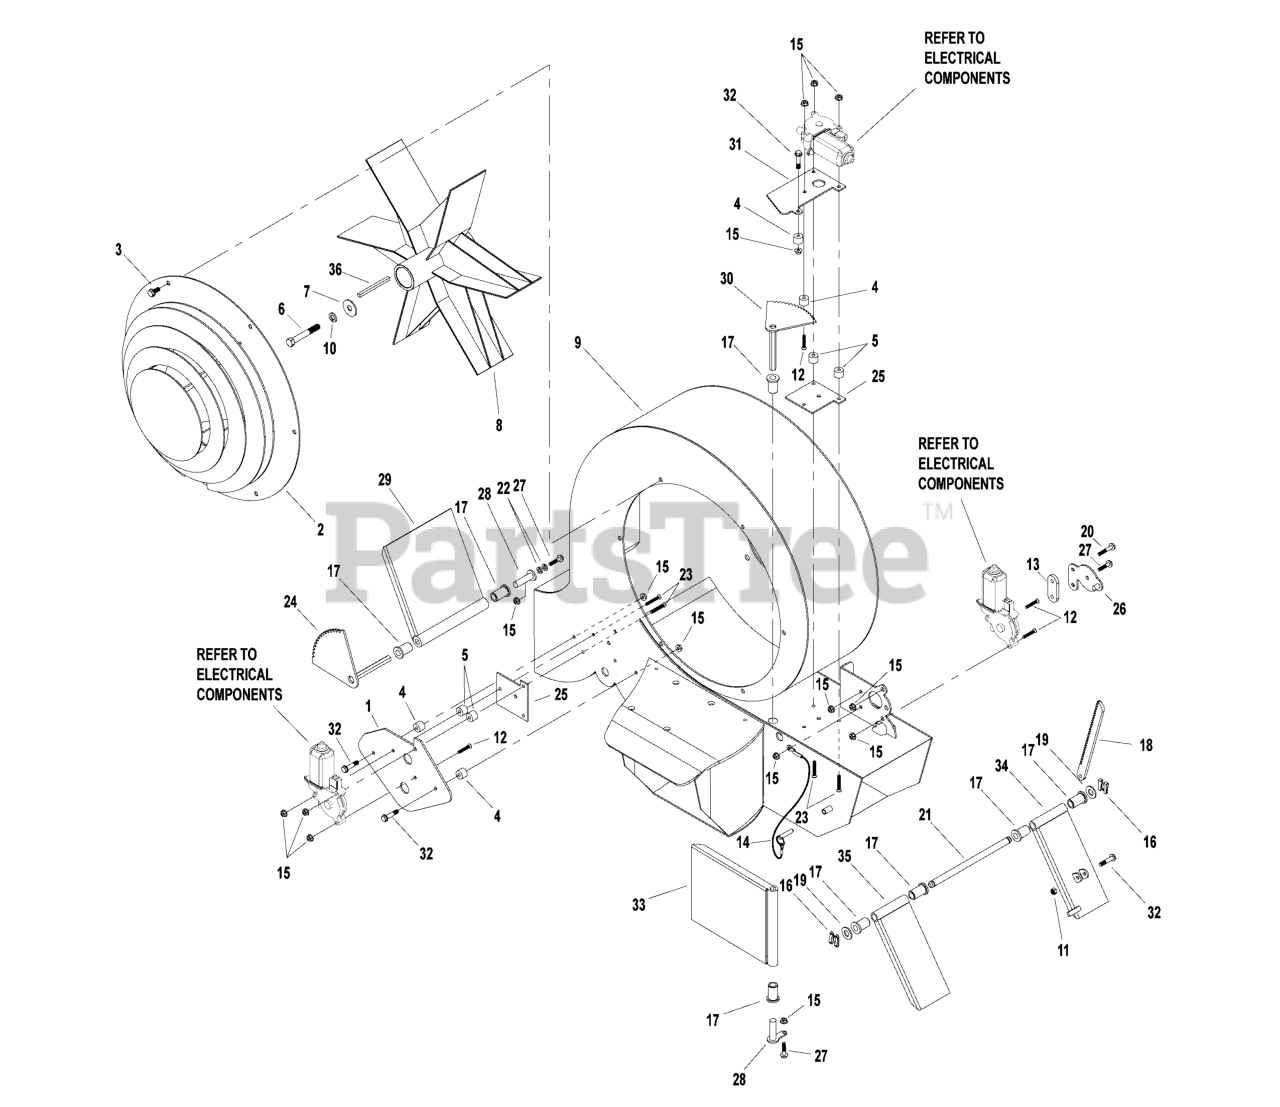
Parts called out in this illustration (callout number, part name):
1	PLATE, RIGHT DEFLECTOR COVER - BLK
2	WELD, SAFETY COVER X3 - BLK
3	BOLT, 5/16-18 X 3/4, FLANGE, CZ
4	SPACER, .265 X .50 X .320, CZ
5	SPACER, .265 X .50 X .483, CZ
6	BOLT, 7/16-20 X 2, GD8, PHOS
7	WASHER, IMPLR, 1-3/4OD X 7/16ID
8	WELD, IMPELLER, W/VANGUARD ENG (XF1737)
9	WELD, BLOWER HOUSING , X3 - RED
10	WASHER, 7/16, Split Lock, Zinc/Clear
11	NUT, 1/4-20 HEX NYLON LOCK
12	SCREW, 1/4-20 X 1-1/4, ALLEN, SS
13	PLATE, RACK SPACER (101-16-2029)
14	Z DEFLECTOR PIN RETAINING CABLE (Pin & Lanyard Assembly)
15	NUT, 1/4-20 HEX SERR. FLANGE
16	CLIP, SAFETY
17	BUSHING, 1/2 X 3/4 X 1F
18	PLATE, DEFLECTOR RACK,CZ
19	WASHER, 1/2 SAE
20	BOLT, 1/4-20 X 1-1/2, FLANGE, CZ
21	ROD, DEFLECTOR SUPPORT 1/2 X 7.50
22	WASHER, 1/4 LOCK
23	SCREW, 1/4-20 X 1-3/4, ALLEN, SS
24	WELD, UNIVERSAL DEFLECTOR GEAR
25	PLATE, DEFLECTOR SPACER (X310-2052)
26	WELD, RACK KEEPER, CZ
27	BOLT, 1/4-20 X 3/4, FLANGE, CZ
28	PIN, DEFLECTOR, RIGHT
29	WELD, RIGHT DEFLECTOR, X3, CZ
30	WELD, UNIVERSAL DEFLECTOR GEAR
31	PLATE,FW DEFLECTOR MOTOR MNT (X310-2043)
32	SCREW, #8-32 X 3/8, ALLEN, SS
33	FORWARD DEFLECTOR X3, CZ
34	WELD, LEFT POWER DEFLECTOR, FB2000, CZ
35	WELD, LEFT SLAVE DEFLECTOR, FB2000,CZ
36	KEY, 1/4SQ X 3-3/8
